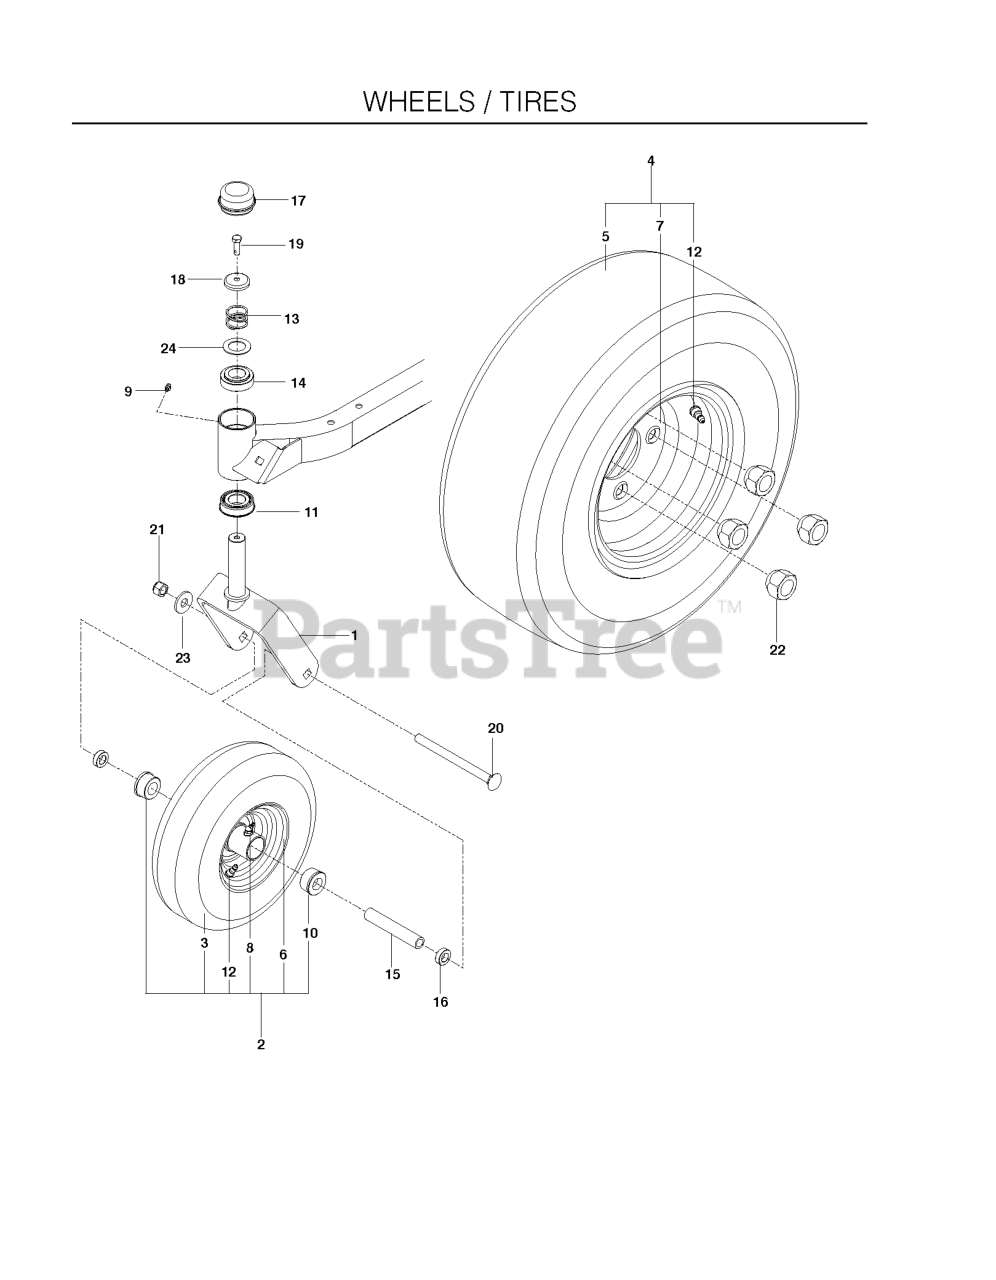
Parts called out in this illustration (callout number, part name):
1	CASTER DK BLUE
2	TIRE, CASTER, COMPLETE
3	TIRE, 4. 10-5.4 PLY
4	WHEEL ASSY REAR 18 X 7.5-8
5	TIRE-KENDA18X7.5X8 4PLY
7	RIM, 5.38 X 08
8	ZERK
9	ZERK, 3/16, DRIVE IN
10	BUSHING, WHEEL, 3/4"
11	BEARING FLANGED
12	VALVE STEM TR-412
13	SPRING, CASTER
14	BUSHING, CASTER
16	SPACER, 5/16"
17	GREASE CAP
18	PLUG, CASTER
19	5/16-18X1 HHB G5W/NY
20	RHSNB 1/2-13 X 6.50 GR5 ZD
21	NUT 1/2-13 HEX CNTRLK GR 5 ZD
22	LUG NUT 1/2F
23	WASH USS FLAT 1/2
24	WASHER, 1.025 ID X 1.64
